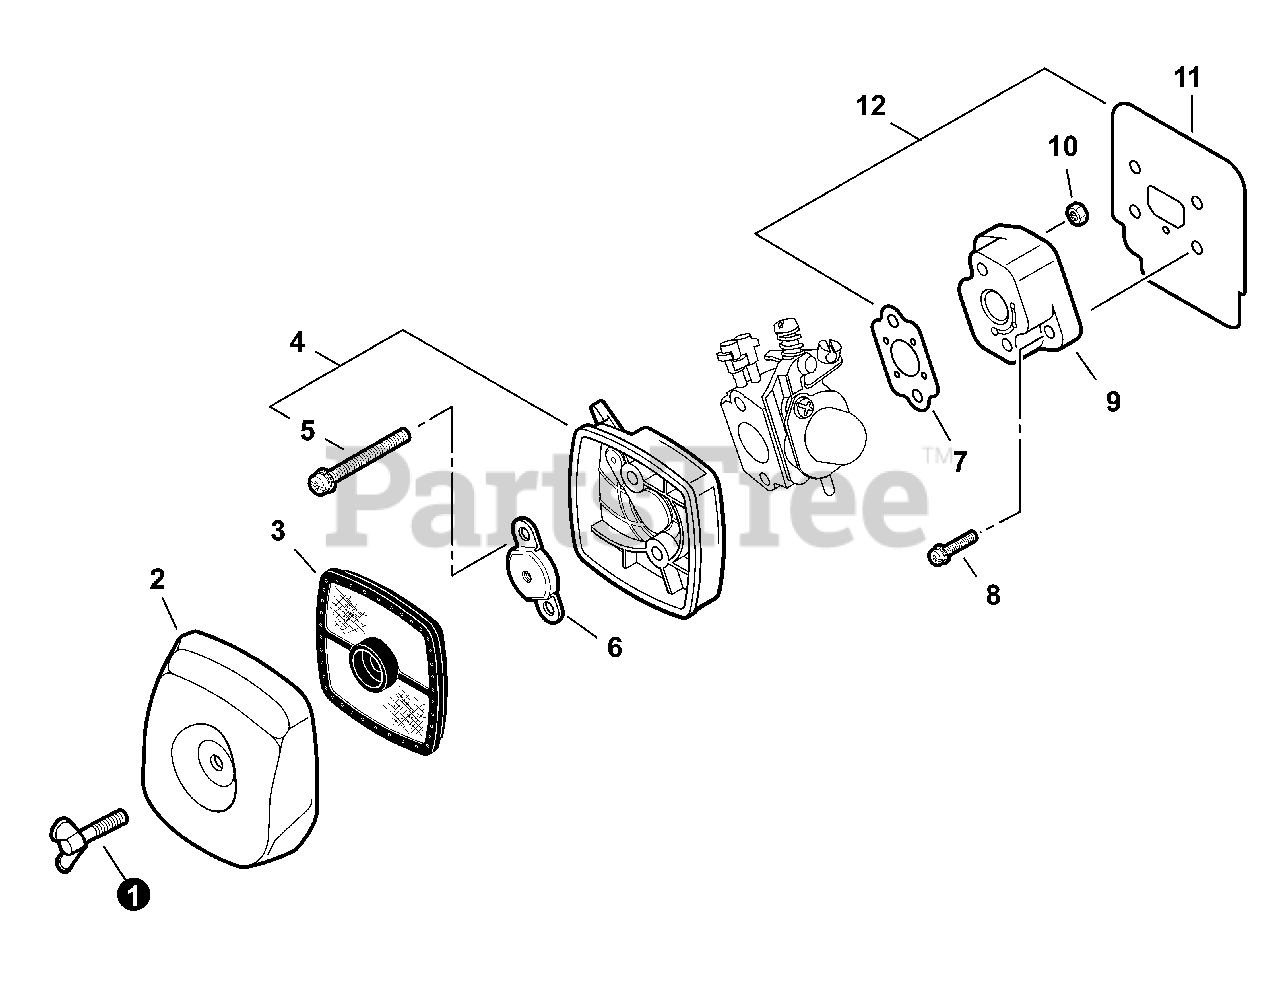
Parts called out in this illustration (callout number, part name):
1	BOLT, WING 5×20
2	COVER, AIR FILTER - GRAY
2	COVER, AIR FILTER - BLACK
3	FILTER, AIR - DOUBLE LAYER
4	CASE, AIR FILTER - GRAY
4	CASE, AIR FILTER - BLACK
5	SCREW 5×65
6	PLATE, PREVENT
7	GASKET, INTAKE
8	SCREW 5×20
9	INSULATOR, INTAKE
11	HEAT SHIELD, INTAKE
12	GASKET KIT
